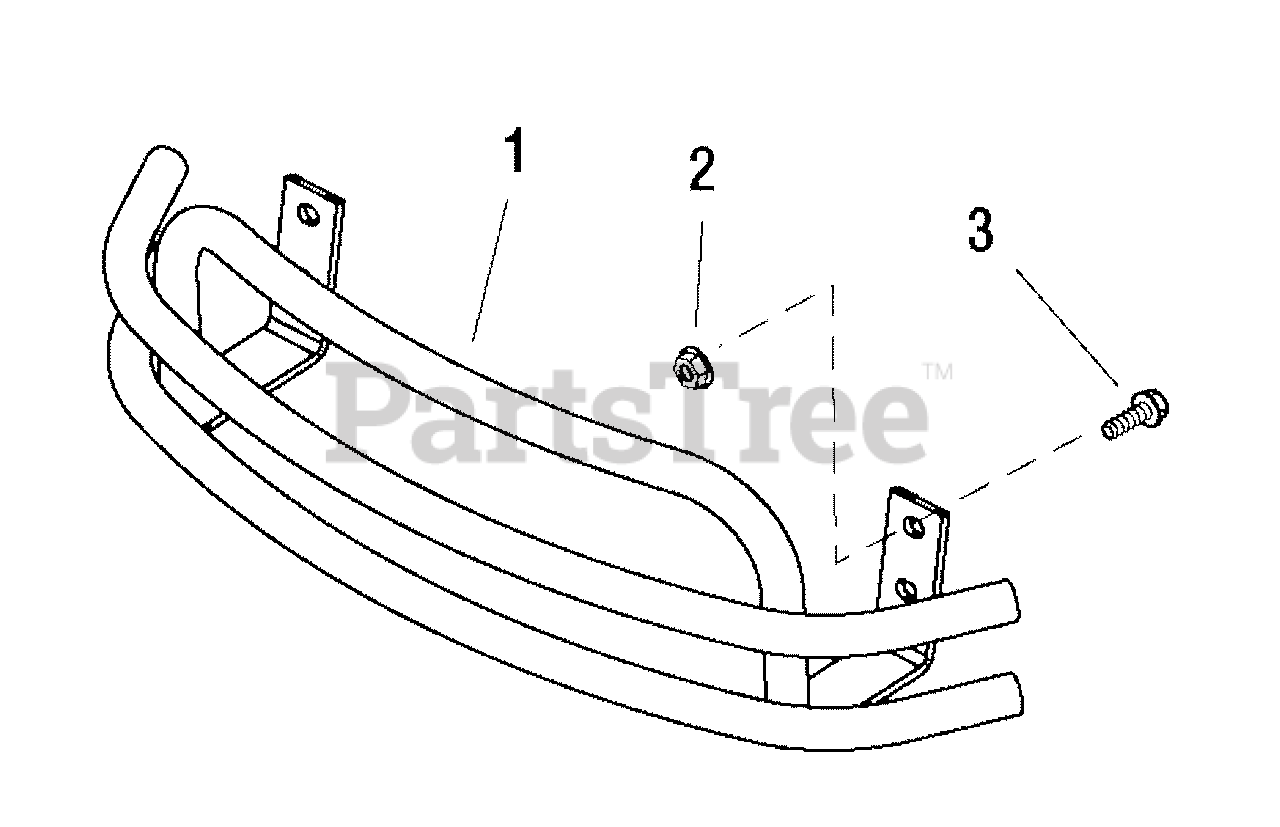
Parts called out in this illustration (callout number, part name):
1	BUMPER ASSEMBLY
2	NUT, Hex, Flange Lock, 5/16-18
3	CAPSCREW, Flange Lock, 5/16-18 x 3/4
